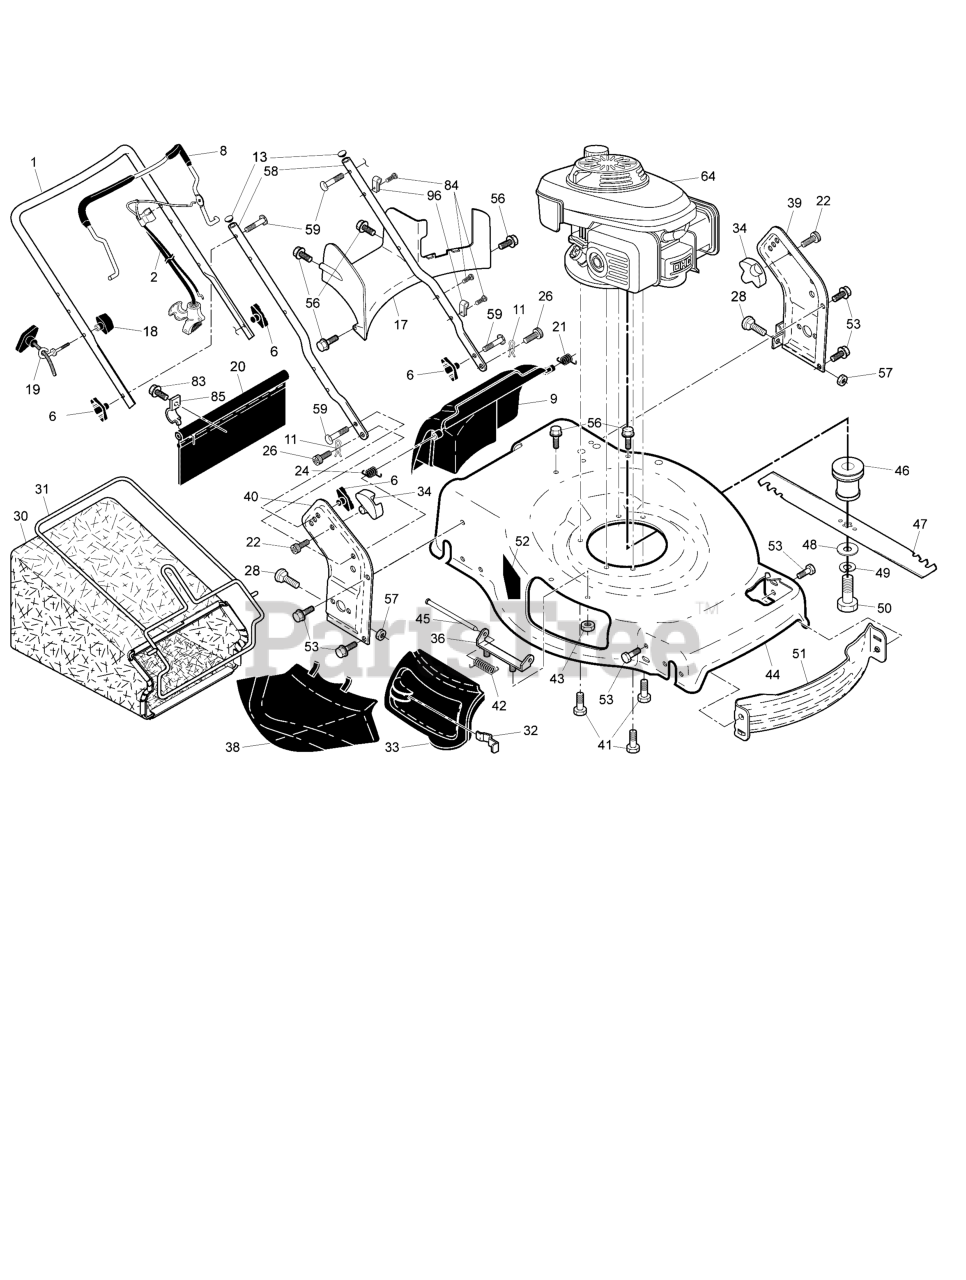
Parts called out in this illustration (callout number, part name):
1	HANDLE, Upper
2	CABLE, Engine Zone Control
6	KNOB, Handle, Standard
8	BAR, Control
9	ASSEMBLY, Rear Door
11	HAIRPIN
13	PLUG, Handle
17	BAFFLE, Rear
19	GUIDE, Rope
20	SKIRT, Rear
21	Spring, Rear Door, LH, Black
22	Screw, Panhead, Torx #20
24	Spring, Rear Door, RH, Grey
26	SCREW, Door/Handle Pivot
28	BOLT, Carriage, 5/16-18 x 5/8
30	GRASSBAG
31	FRAME, Grass Bag
32	Latch, Mulcher Door
33	DOOR, Mulcher
34	BRACKET, Pivot
36	Hinge Bracket Assembly
38	Discharge Deflector
39	BRACKET, Handle, Left
40	BRACKET, Handle, Right
41	SCREW, 3/8 Hex HD Thread Rolled
42	Spring, Torsion
43	Nut, Hex, Flanged 1/4-20
44	KIT, Lawn Mower Housing
45	HOSE-FUEL
46	ADAPTER / PULLEY, Blade
47	Blade, 22"
48	WASHER, Hardened
49	WASHER, Helical
50	Screw, Machine, Hex Head, 3/8-24 x 1-3/8, Grade 8
51	Front Baffle
52	DECAL, CPSC, Danger, Cut Finger
53	SCREW, 5/16-18
56	Screw, Hex Washer Head, #13 x 3/4
57	Nut, Hex 3/8-16
58	HANDLE, Lower
59	Bolt, Carriage 1/4-20 x 1-1/2
64	* ENGINE - Honda, Model Number GCV160-LAOS3B
84	FASTENER, Push
85	BRACKET, Mounting, Rear Skirt
96	Clip, Cable
